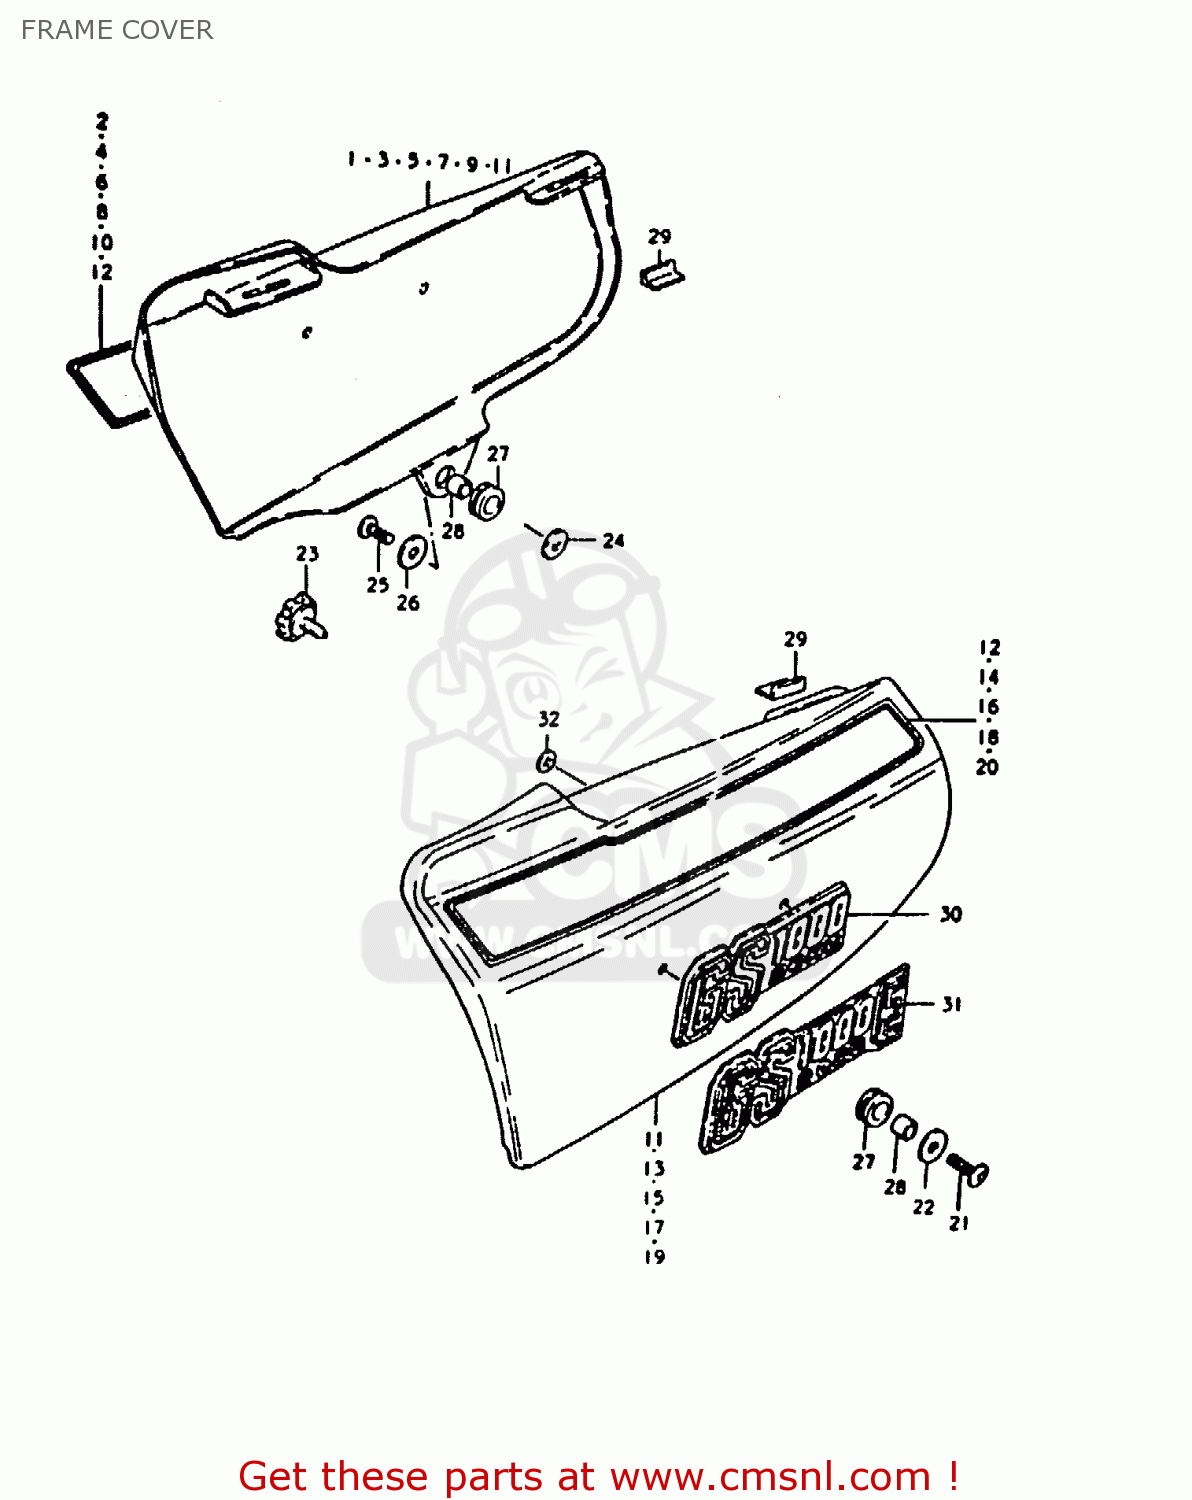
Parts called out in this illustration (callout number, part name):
1	COVER, FRAME RH (RED)
2	TAPE, RH
3	COVER, FRAME RH (BLUE)
4	TAPE, RH
5	COVER, FRAME RH (BLACK)
6	TAPE, RH
11	COVER, FRAME LH (RED)
12	TAPE, LH
13	COVER, FRAME LH (BLUE)
14	TAPE, LH
15	COVER, FRAME LH (BLACK)
16	TAPE, LH
21	SCREW
22	WASHER (6.5X18X1.6)
27	CUSHION
28	SPACER (6.8X10X10)
29	CUSHION,FRAME COVER
30	EMBLEM,FRAME COVER
31	EMBLEM,FRAME COVER
32	NUT
